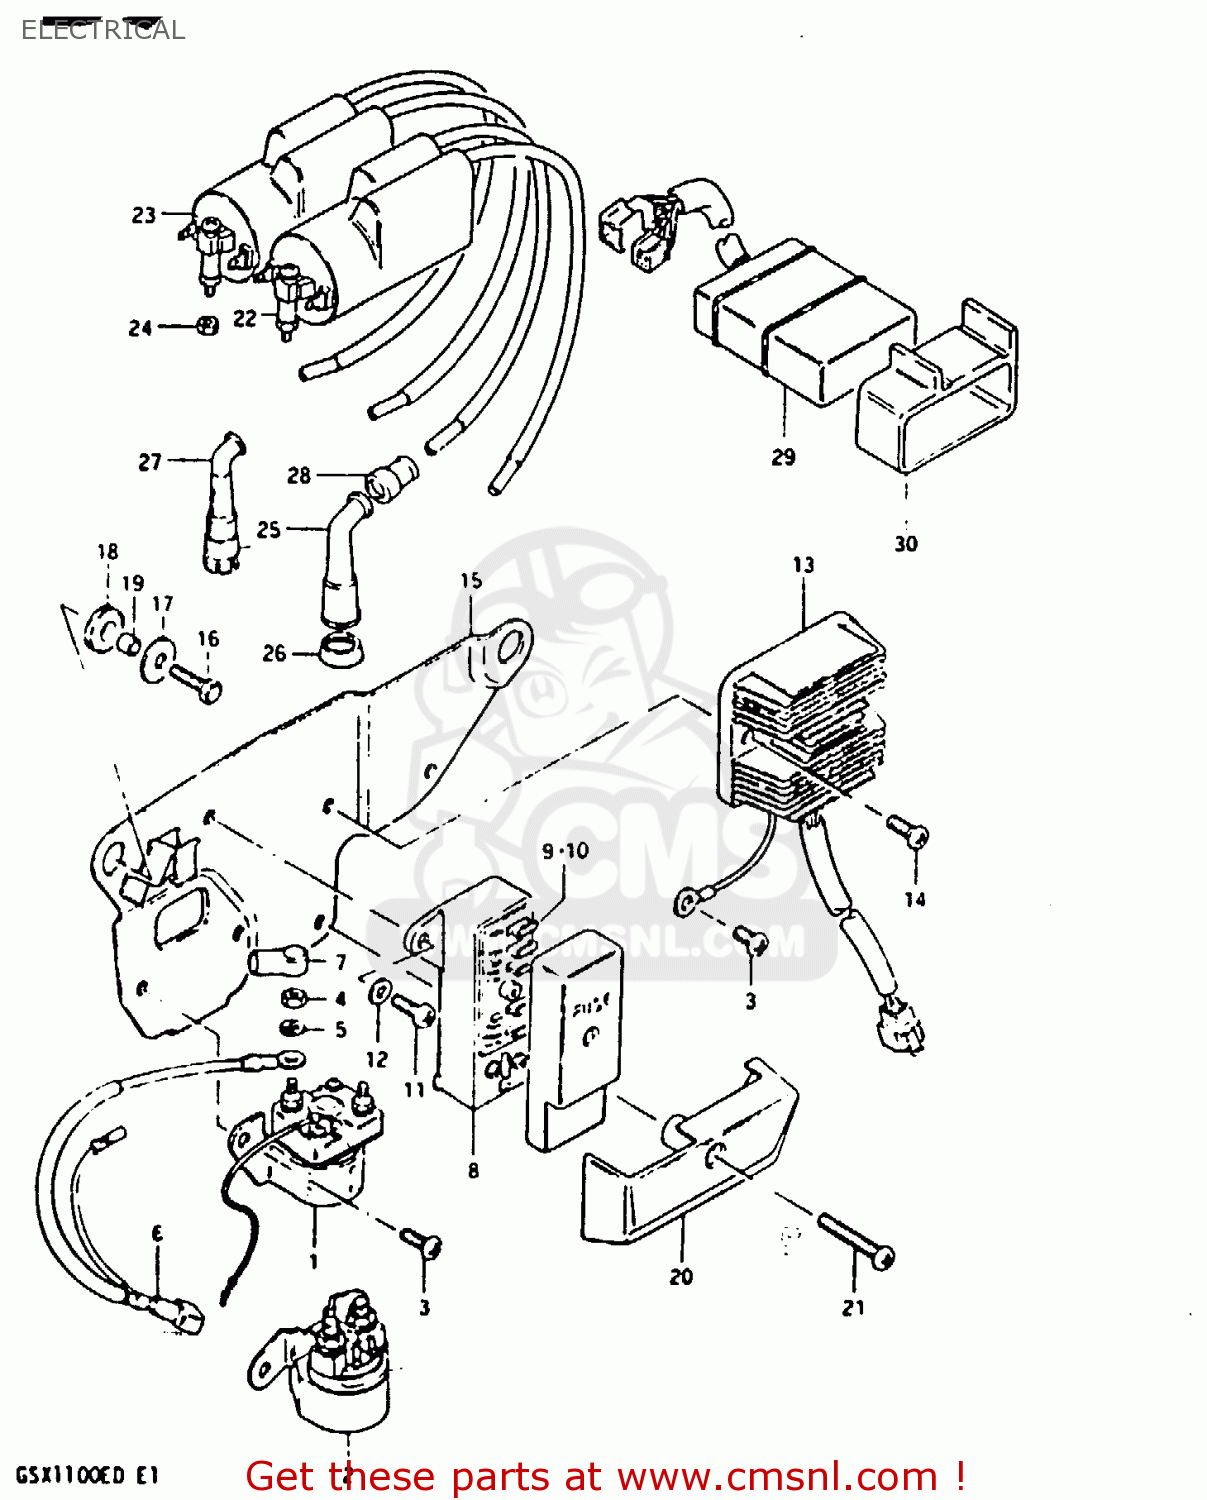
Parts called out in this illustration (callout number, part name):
1	RELAY ASSY,STARTING MOTOR
2	RELAY ASSEMBLY,STARTING MOTOR
3	SCREW
4	NUT 6MM
5	LOCK WASHER
6	CORD,BATTERY MINUS
7	CAP,STARTER RELAY
8	BOX ASSEMBLY,FUSE
9	FUSE(10A)
10	FUSE(15A)
11	SCREW
12	WASHER
13	RECTIFIER ASSEMBLY
14	SCREW 6X12
15	HOLDER COMP,ELECTRONIC PARTS
16	BOLT, UPPER
17	WASHER (6.5X22X1.6)
18	CUSHION
19	SPACER (7X9X7)
20	COVER,ELECTRIC PARTS HOLDER
21	SCREW (6X35)
22	COIL ASSEMBLY,IGNITION
23	COIL ASSEMBLY,IGNITION
24	NUT
25	CAP ASSY,SPARK PLUG
26	SEAL,SPARK PLUG
28	SEAL,SPARK PLU
29	RELAY,LAMP OUTAGE WARNING
30	STAY,LAMP OUTAGE INDICATOR
